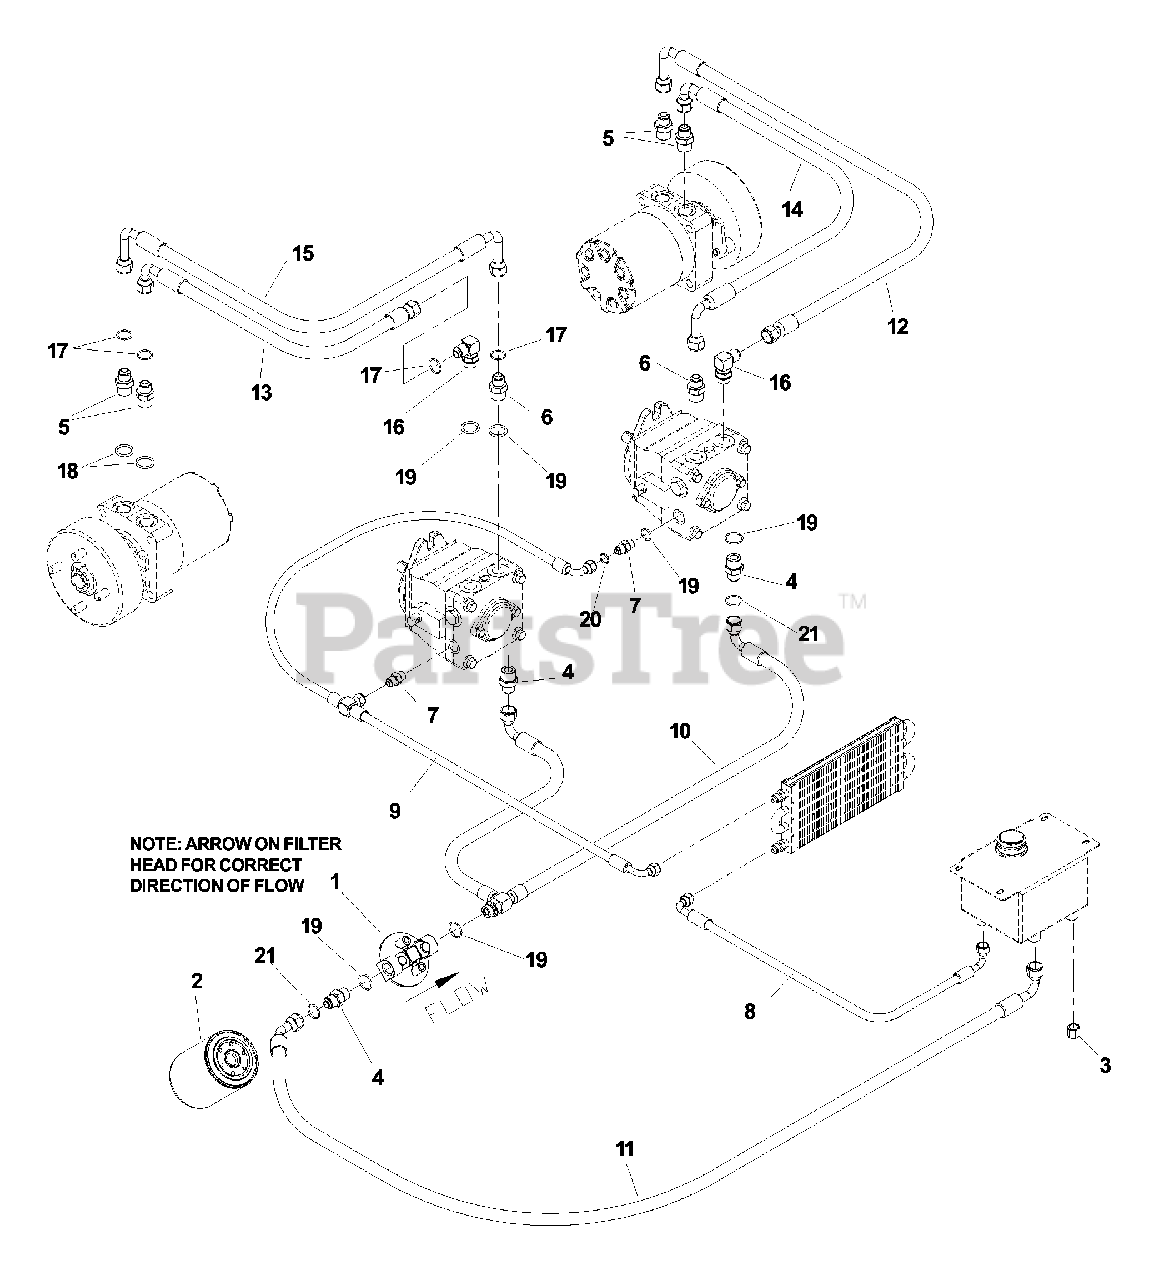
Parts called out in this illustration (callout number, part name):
1	Filter head
3	Cap nut, reservoir drain
4	Straight connector
5	Fitting, wheel motors
6	Fitting, pumps
7	Fitting, pumps (return side)
8	Hose, cooler-reservoir
9	Hose, T, pumps-cooler
10	Hose, T, filter, out-pumps
11	Hose, reservior-filter, in
12	Hose, LL pump-LR mtr
13	Hose, RR pump-RF mtr
14	Hose, LR pump-LF mtr
15	Hose, RL pump-RR mtr
